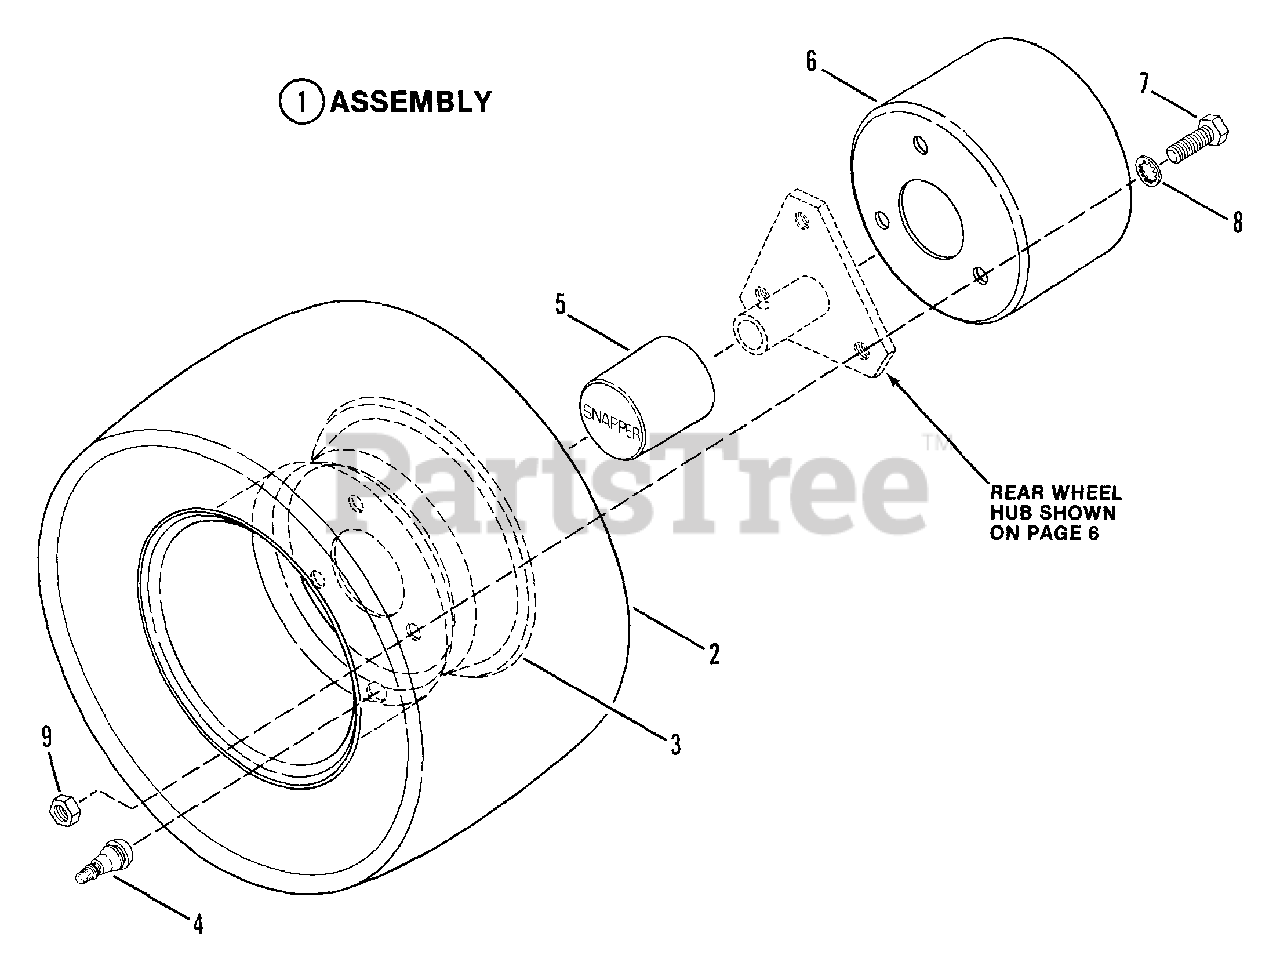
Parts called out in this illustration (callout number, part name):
1	ASSEMBLY, Rear Tire & Rim
2	TIRE, Wide, 16/6.50 x 8
3	RIM, Wide
4	VALVE, Air (Snap-in)
5	HUB-CAP
6	BRAKE DRUM
7	SCREW, 1/2-20 x 1-1/4" Hex Head Cap
8	WASHER, 1/2" Internal Tooth Lock
9	NUT, 1/2-20 Hex
